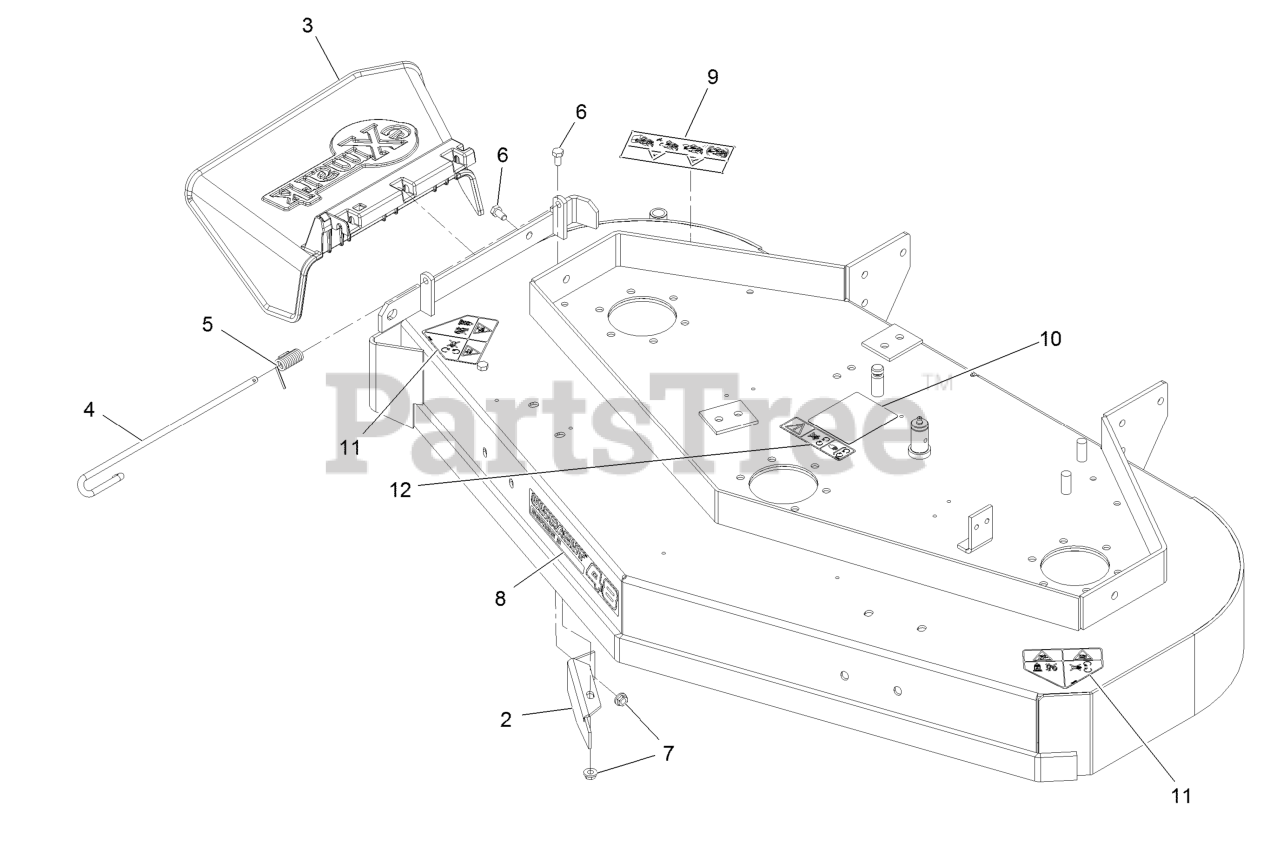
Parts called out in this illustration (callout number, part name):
2	Baffle-Dogleg
3	Deflector-Discharge
4	Pin-Chute
5	Spring, Torsion
6	Screw-HH 5/16-18 X 5/8
7	Nut-Whizlock 5/16-18
8	Decal-Ultracut 48 Series 3
9	Decal-Warning, Bagger
10	Decal-Routing, Belt
11	Decal-Danger
12	Decal-Cover, Missing
